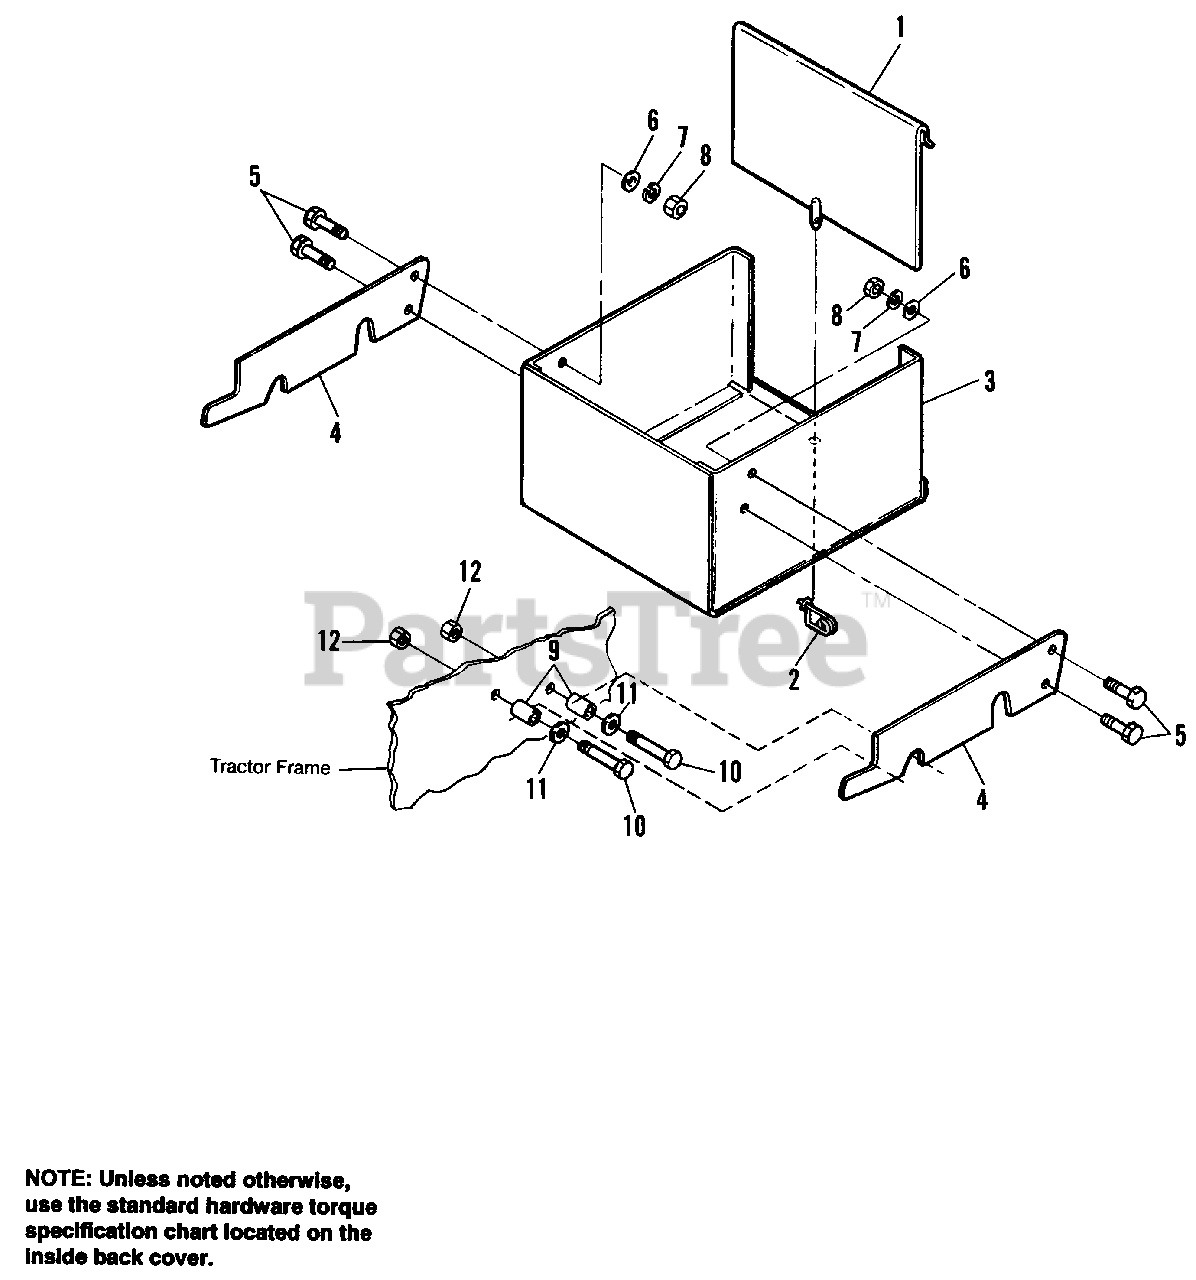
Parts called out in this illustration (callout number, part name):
2	SAFETY CLIP
3	WEIGHT BOX
4	SUPPORT, Side Hitch
5	CAPSCREW, Hex, 3/8-16 x 1-1/4
6	WASHER
7	LOCKWASHER, 3/8
8	NUT, Hex, Full, 3/8-16
10	CAPSCREW, Hex, 1/2-13 x 2-1/2
11	WASHER
12	NUT, Hex, Lock, Esna, 1/2-13
